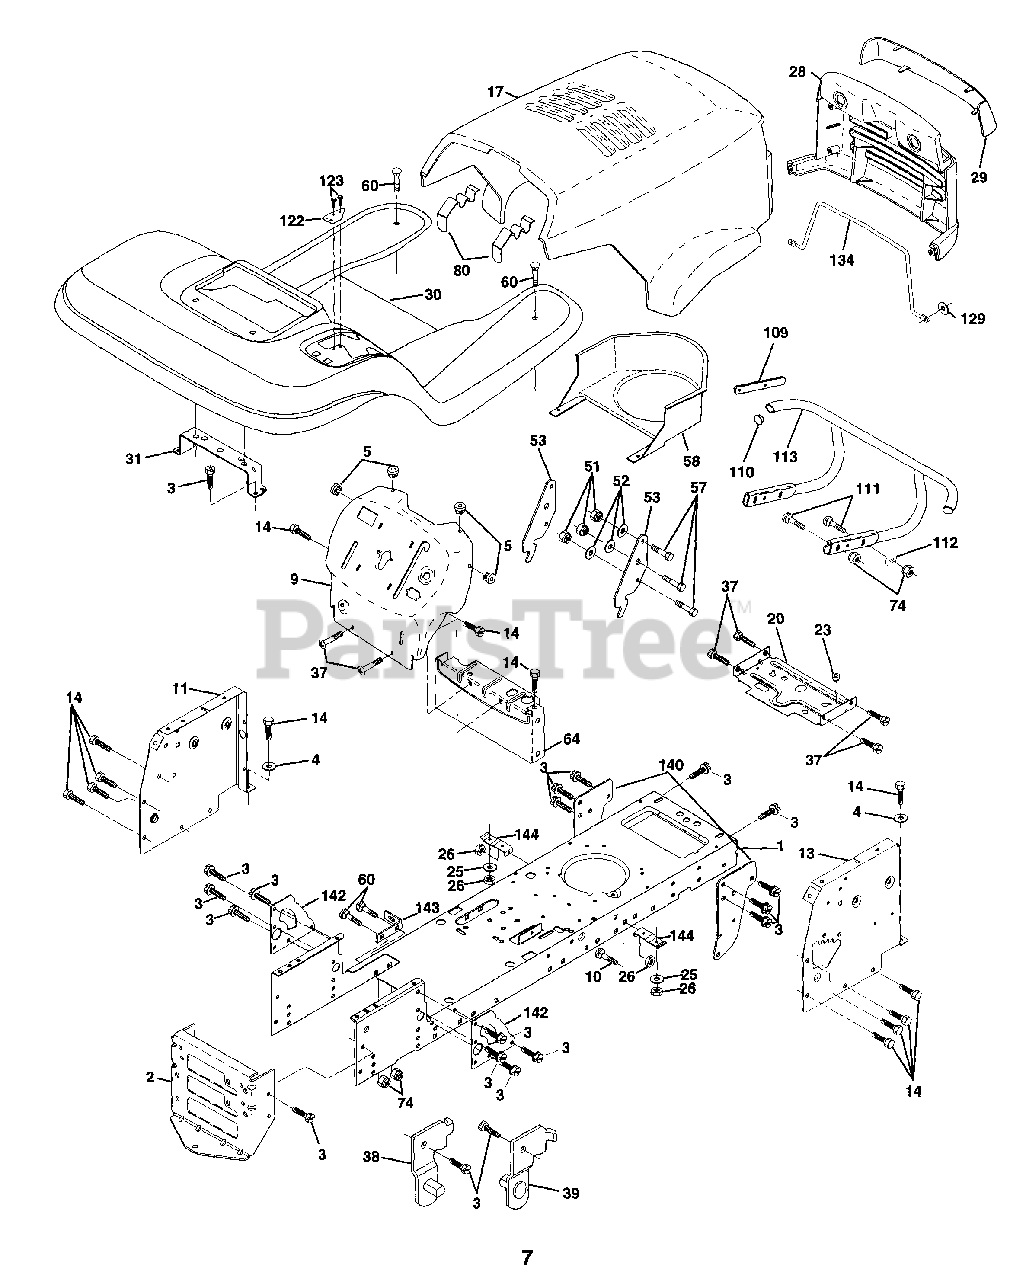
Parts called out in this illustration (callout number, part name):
1	Chassis Weldment
2	Drawbar, Stretch
3	Screw Thdrol 3/8-16 x 3/4 Ty-tt
4	Washer 13/32 x 3/4 x 16 Ga.
5	Bumper Hood/Dash
9	Dash P/L E A Hm NC Sym
10	Bolt Carriage 3/8-16 x 1
11	Panel Dash Lh
13	Panel Dash Rh
14	Screw Thdrol 3/8-16 x 1/2 Ty-tt
17	Hood LT/PL Husqvarna
20	Plate Mtg Battery Fuel Tank Fr
25	Washer 13/32 X 13/16 X 12 Ga
26	Nut Lock Hex W/Ins 3/8-16 Unc
28	Grille LT/PL Husqvarna
29	Lens LT/PL Husqvarna
30	Fender Footrest STLT Pnt
31	Bracket Support Fender
37	Screw Thdrol 6/16-18 x 1/2 TYT
38	Bracket, Asm. Pivot, L.H., Mower Rear
39	Bracket, Asm. Pivot, R.H., Mower Rear
51	Nut Lock Hex W/Ins 1/4-20
52	Washer 9/32 x 7/8 x 16 Ga.
53	Bracket Pnt. Pick off LT/PL Husqvarna
57	Bolt Hex 1/4-20 x 3/4
58	Air Duct Engine P/L
60	Bolt Rdhd Sqnk 3/8-16unc x 3/4
64	Dash Lower STLT
74	Nut Crownlock 3/8-16 UNC
80	Latch Hood Plm Husqvarna
109	Bracket Extension Bumper
110	Plug Plastic
111	Belt Rdhd 3/8-16 UNC x 1-1/2
112	Washer 13/32 x 13/16 x 10 Ga.
113	Bumper Asm
129	Washer 9/32 x 5/8 x 16 Ga.
134	Rod Support Hood LT/PL Husq.
140	Bracket Chassis Front 7 Ga.
142	Plate Reinforcement STLT
143	Bracket Swaybar Chassis
144	Bracket Pnt Footrest STLT
146	Screw Torx Hd Thd 5/16-18 UN-24
